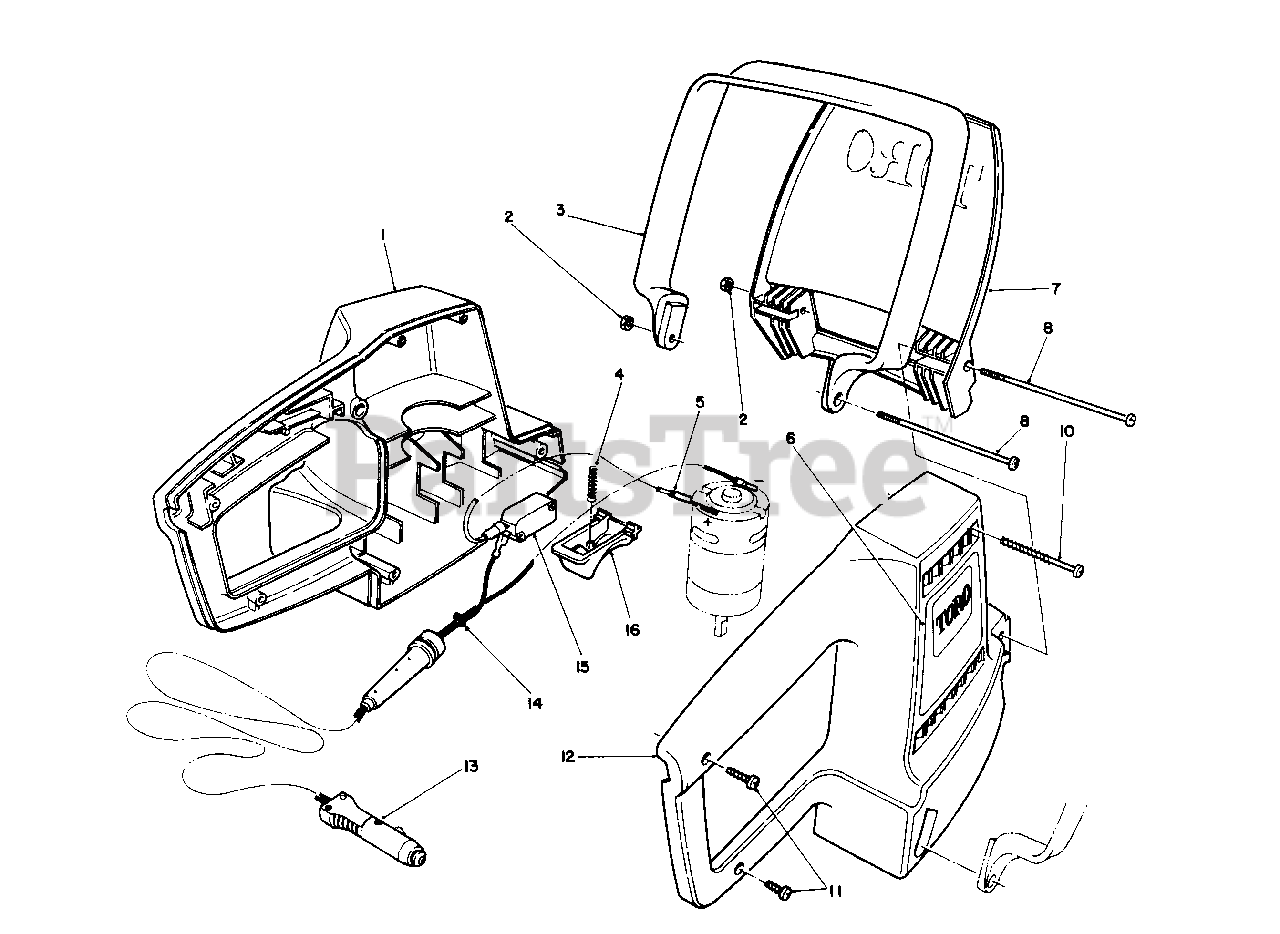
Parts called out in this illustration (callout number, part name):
1	Housing-Handle, L.H.
3	Handle-Assist
5	Wire Assembly
6	Decal-Toro
10	Screw-Thread Forming
11	Screw-Thread Forming
12	Housing-Handle, R.H.
13	Cord-Handle
16	Trigger-Switch
